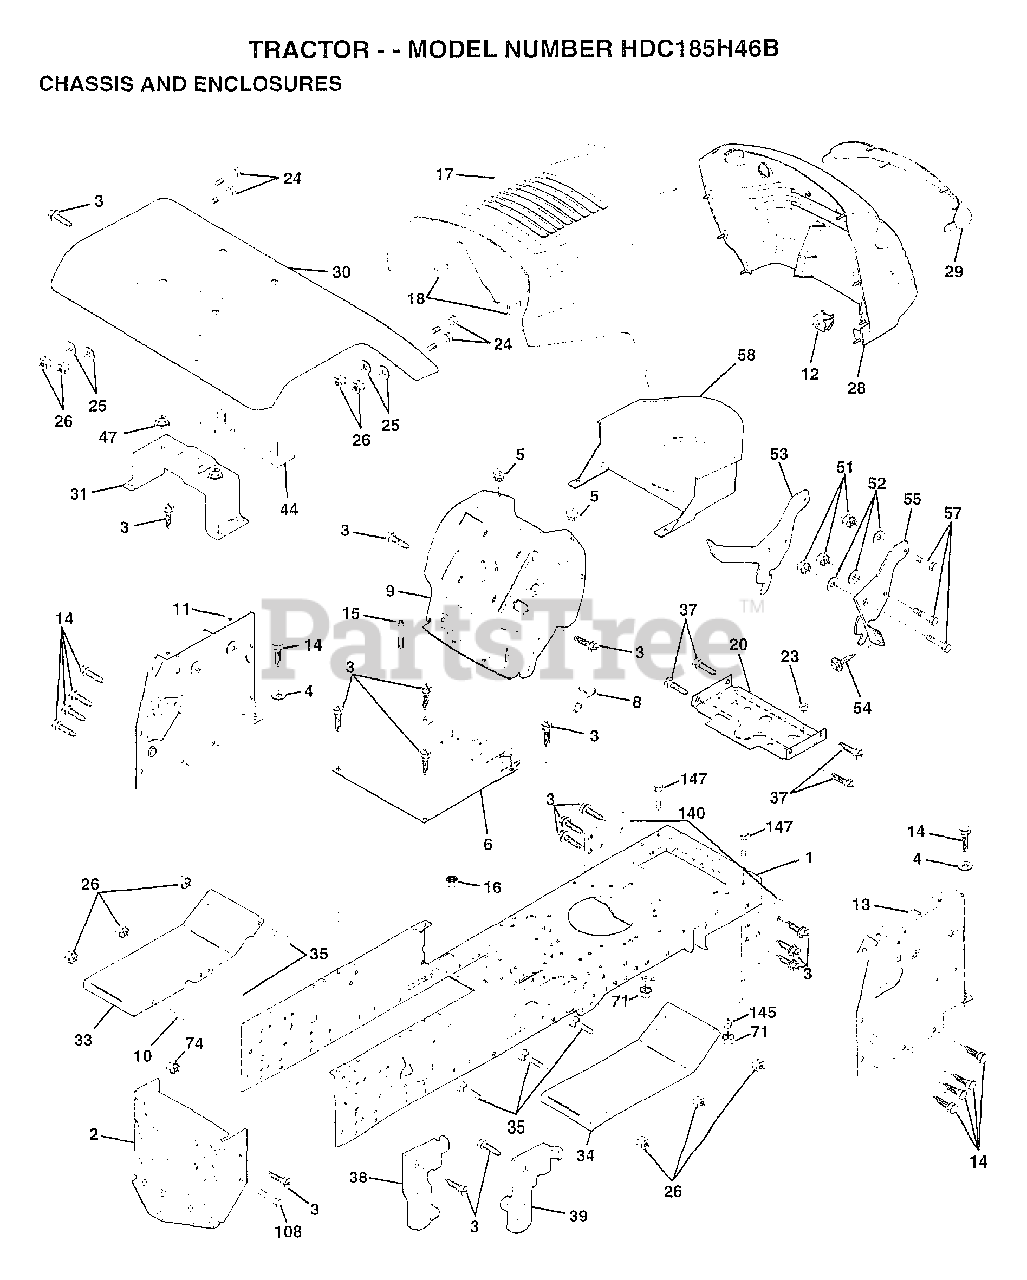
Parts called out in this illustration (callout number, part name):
1	CHASSIS ASM
3	SCREW
4	WASHER
5	BUMPER-HOOD/DASH
6	SADDLE
8	"CLIP,INSULATOR"
9	DASH SILKSCREEN
11	PANEL ASM DASH LH
12	CLIP.TINNERMAN
13	PANEL DASH RH
14	SCREW LT
15	SCREW
17	"HOOD W/TRIM,MS428"
20	"PLATE-MTG,BATT/FU"
24	BOLT
25	WASHER
26	NUT
28	GRILLE-MS428
29	LENS GRILLE
30	"FENDER WS,FTK"
31	BRKT.ASM.FENDER
33	FOOTREST PNT LH
34	FOOTREST.RH.LT/GT
35	BOLT
37	SCREW LT
38	BRACKET ASM LH
39	BRACKET ASM RH
44	STRAP ASM FENDER
47	NUT-PUSH YT
51	NUT
52	WASHER
53	BRACKET.GRILLE.LH
55	BRACKET.GRILLE.RH
58	DUCT.AIR.B&S.18HP
140	BRKT SUSPENSION
145	"ROD POVOT,CHASSIS"
147	BOLT LT
